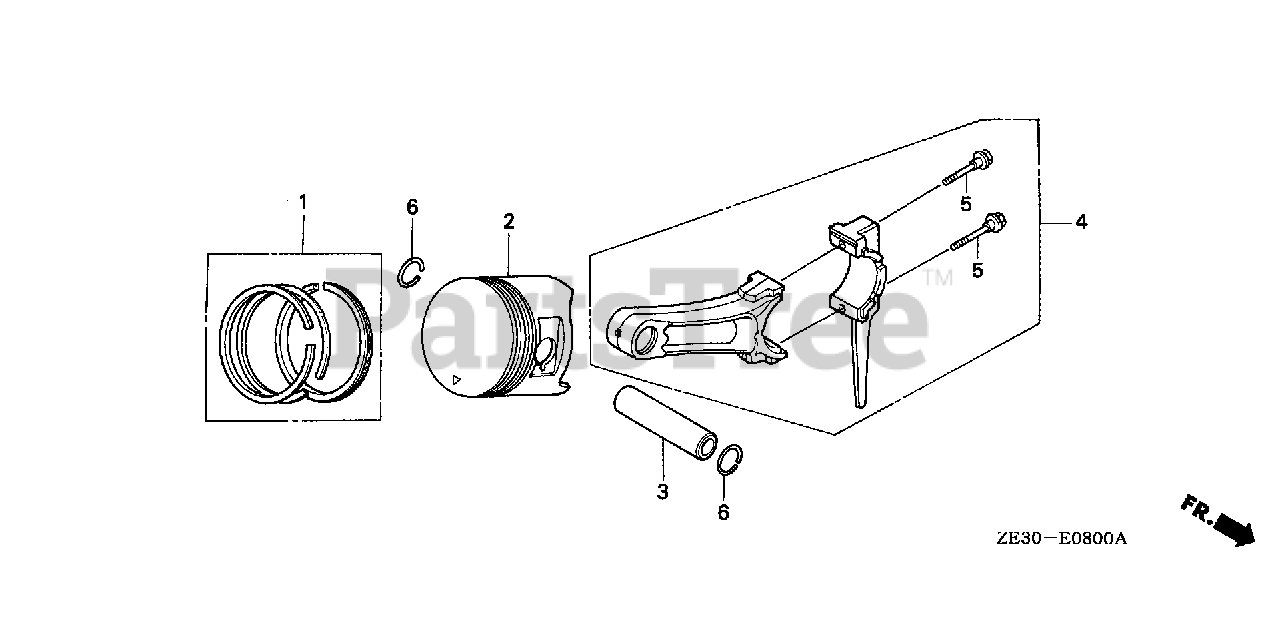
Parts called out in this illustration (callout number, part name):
1	RING SET, PISTON (STD) (NIPPON)
1	RING SET, PISTON (0.25) (NIPPON)
1	RING SET, PISTON (0.50) (NIPPON)
1	RING SET, PISTON (0.75) (NIPPON)
2	PISTON (STD)
2	PISTON (0.25)
2	PISTON (0.50)
2	PISTON (0.75)
3	PIN, PISTON
4	ROD ASSY., CONNECTING (STD)
4	ROD ASSY., CONNECTING (0.25 LOWER SIZE)
5	BOLT, CONNECTING ROD
6	CLIP, PISTON PIN (20MM)
